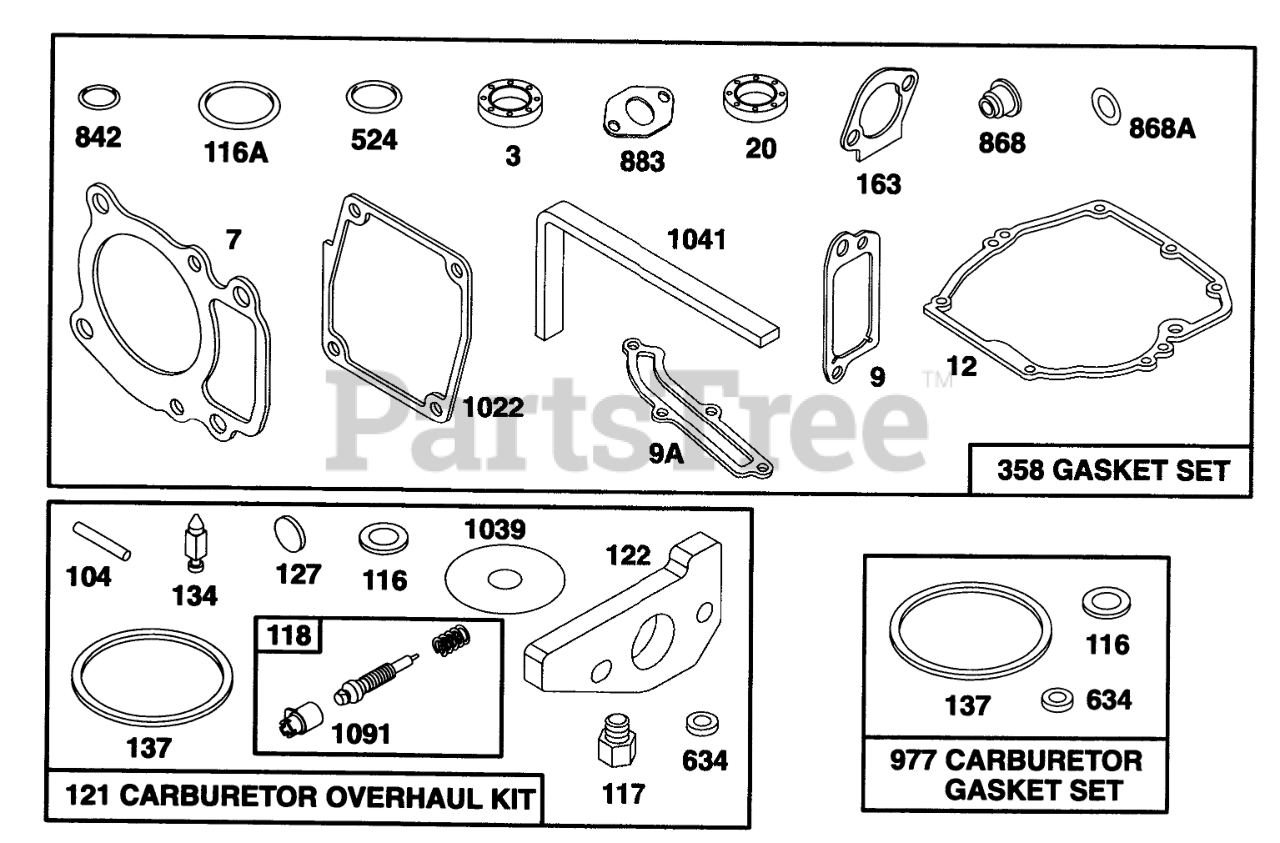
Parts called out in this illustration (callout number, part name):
3	SEAL - OIL
7	CYLINDER HEAD GASKET
9	BREATHER GASKET
9A	GASKET-BREATHER
12	ENGINE BASE GASKET
20	SEAL-OIL
104	FLOAT HINGE PIN
116	SEALING GASKET
116A	O RING SEAL
117	Jet-Main
118	VALVE/SPRING - NEEDLE
121	KIT-CARBURETOR OVERHAUL
122	ADAPTER ASSEMBLY
127	PLUG - WELCH
134	Valve-Inlet (Includes Seat)
137	FLOAT BOWL GASKET
163	AIR CLEANER GASKET
358	GASKET SET
524	O-RING
634	SEAL WASHER
842	O-RING
868	SealAssy-Valve
868A	Seal-Valve
883	EXHAUST GASKET
977	CARBURATOR GASKET SET
1022	Gasket-RockerCover
1039	FLOAT LIMITER
1041	SEAL - FOAM
1091	CAP - LIMITER
